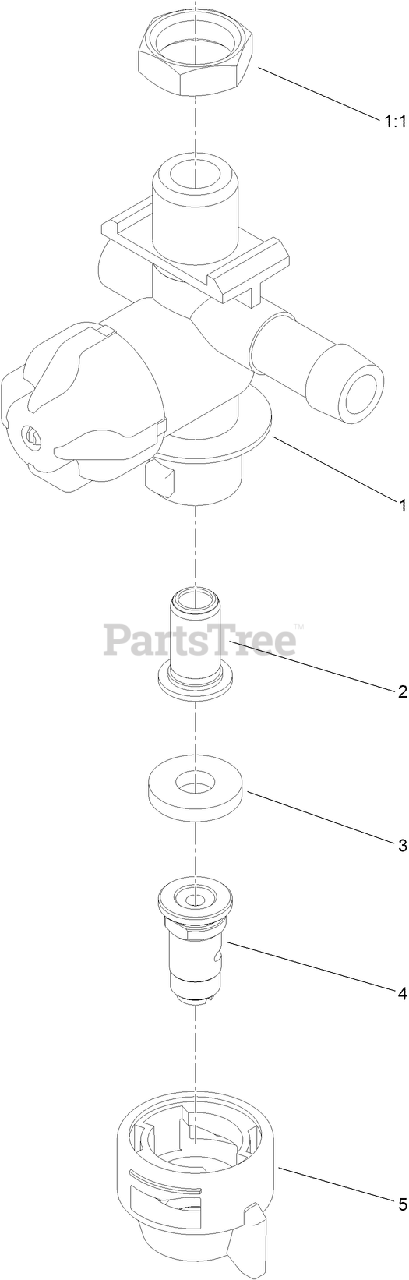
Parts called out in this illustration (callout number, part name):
1	LH NOZZLE BODY ASM
1:1	NUT-NYLON
2	STRAINER-TIP
3	GASKET-SEAL
4	NOZZLE-SPRAY, WHITE
5	CAP-NOZZLE
